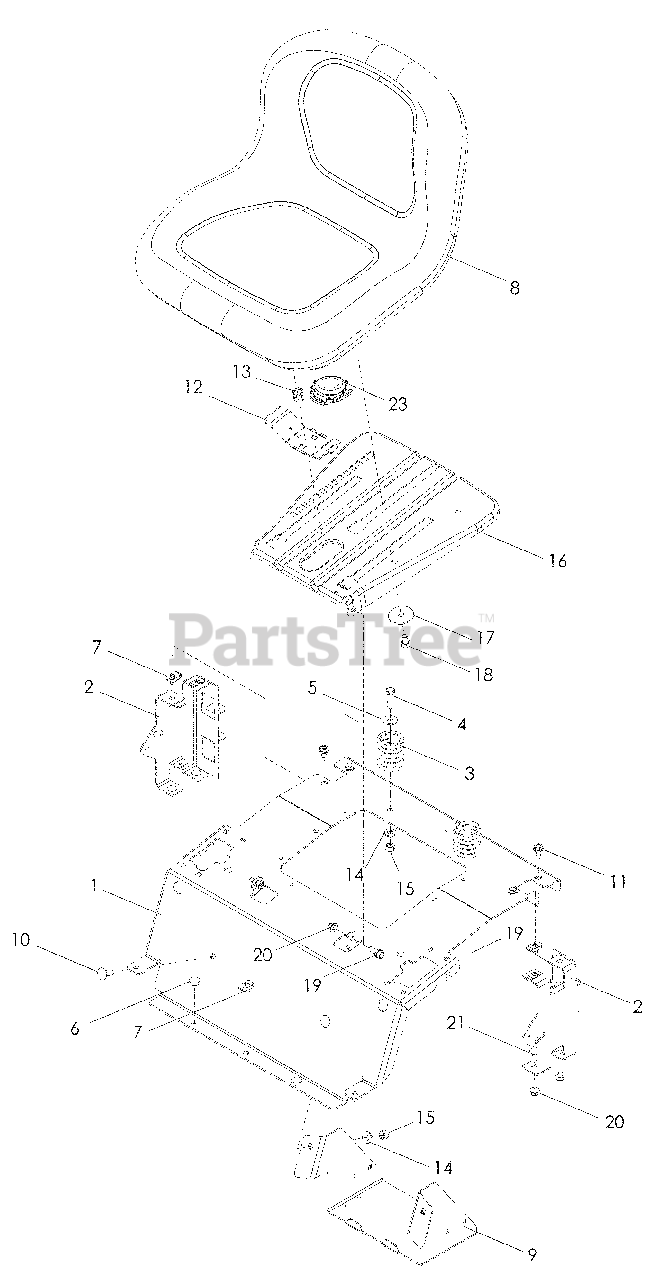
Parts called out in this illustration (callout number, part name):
1	SUPPORT, SEAT, FLT
2	SUPPORT, SEAT RR
3	SPRING, SEAT
4	HCS 3/8-16 x 1¼
5	WASHER 3/8 FLT STD
6	GROMMET, BUMPER
7	RETAINER, U TYPE
8	SEAT
9	BOX, BATTERY
10	RHSNB 3/8-16 x 1
11	BOLT 5/16-18 x ¾ THD FRM
12	HANDLE, SLIDE
13	SPRING, LATCH
14	WASHER 3/8 SAE FLT
15	NUT 3/8-16 HEX NYLOC
16	PAN, SEAT
17	WASHER 3/8 SPECIAL
18	HCS 3/8-16 x 5/8
19	BOLT 5/16-18 SHOULDER
20	NUT 5/16-18 FLANGE NYLOC
21	RHSNB 5/16-18 x ¾
22	BOLT 5/16-18 x 2¼ CARRIAGE
23	SWITCH, SEAT
